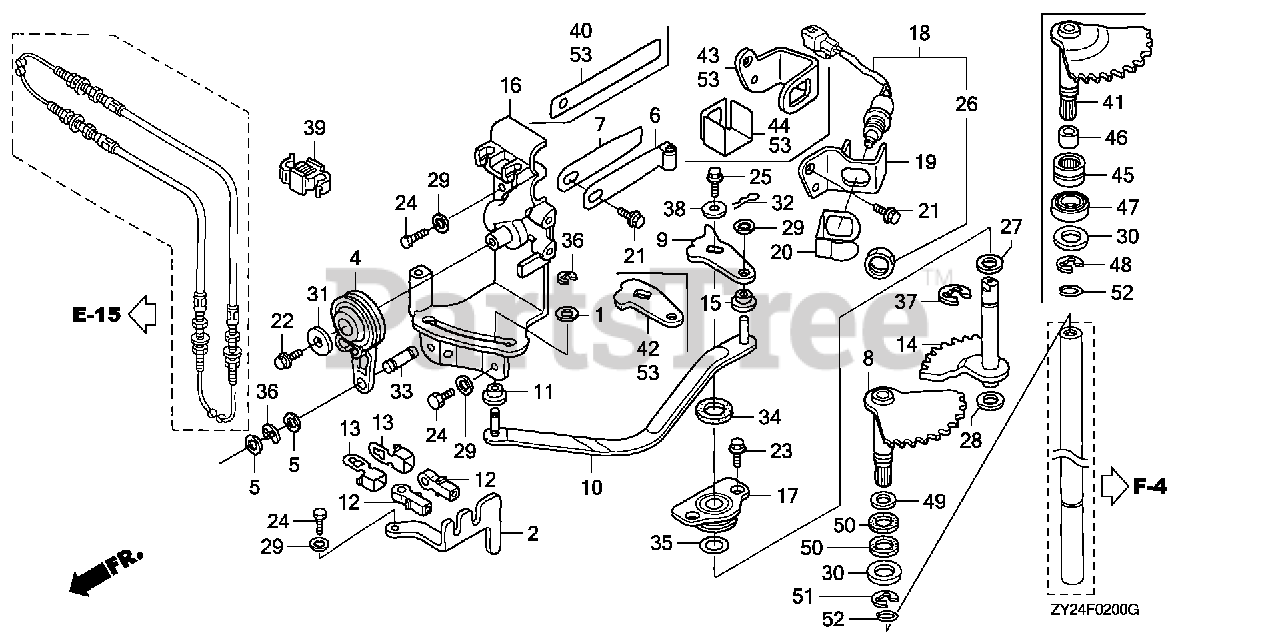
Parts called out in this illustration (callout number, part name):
1	WASHER, AIR CLEANER COVER SETTING
2	PLATE, REMOTE CONTROL CABLE
4	ARM, THROTTLE
5	WASHER, PIVOT
6	SPRING, CLICK
11	COLLAR, SHIFT SLIDER
12	PIVOT, SHIFT
13	PLATE, LOCK
14	SHAFT, SHIFT (B)
15	BUSH, SHIFT ARM
16	BRACKET, SHIFT LINK
17	HOLDER, SEAL
18	SWITCH ASSY., NEUTRAL
21	BOLT, FLANGE (6X14) (CT200)
22	BOLT, FLANGE (6X12)
23	BOLT, FLANGE (6X11)
24	BOLT, HEX. (6X16)
25	BOLT, FLANGE (6X16)
26	NUT, HEX. (20MM)
27	WASHER, THRUST (14MM)
28	WASHER, SHIFT SHAFT
29	WASHER, PLAIN (6MM)
31	WASHER, PLAIN (6MM)
32	PIN, SNAP (6MM)
34	OIL SEAL (14X26X6)
35	O-RING (26.9X2.4) (NOK)
36	E-RING (4MM)
37	E-RING (12MM)
38	WASHER, PLAIN (6MM)
39	CLIP A, WATER VALVE SOLENOID
40	SPRING, CLICK ASSIST
41	SHAFT, SHIFT (A)
42	ARM, SHIFT
43	BRACKET, NEUTRAL SWITCH
44	COVER, NEUTRAL SWITCH
45	BEARING, NEEDLE (20X28X13) (SOLID)
46	RING (INNER) (15X20X13)
47	SEAL, WATER (14X26X8)
48	E-RING (10MM)
52	RING, STOPPER
